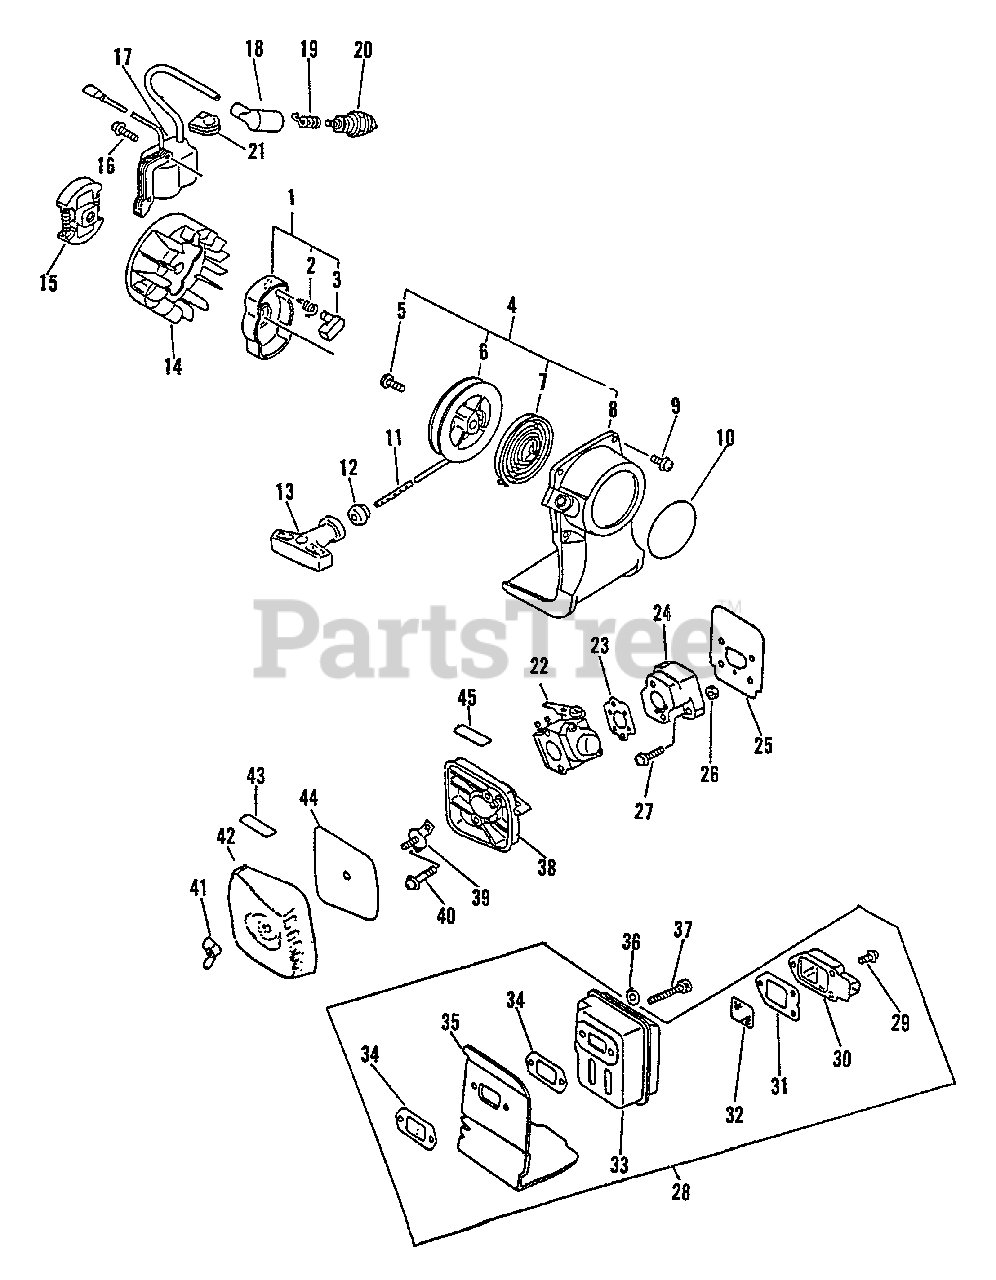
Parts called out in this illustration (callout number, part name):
1	PAWL ASSY, STARTER
2	SPRING, RETURN
3	PAWL, STARTER - BLACK
4	STARTER ASSY
5	SCREW
6	REEL, ROPE
7	SPRING, RECOIL
8	CASE, STARTER
9	SCREW 4×16
10	LABEL, ECHO
11	ROPE, STARTER
12	GUIDE, ROPE
13	GRIP, STARTER
14	FLYWHEEL
15	CLUTCH ASSY
16	SCREW 4×22
17	COIL, IGNITION
18	CAP, SPARK PLUG
19	TERMINAL, SPARK PLUG
20	SPARK PLUG - BPM7A
22	CARBURETOR - C1U-K16
23	GASKET, INTAKE
24	INSULATOR, INTAKE
25	GASKET, INTAKE
26	NUT M5
27	SCREW 5×20
28	MUFFLER ASSY
29	SCREW 4×10
30	GUIDE, EXHAUST - INNER
31	GASKET, EXHAUST
32	SCREEN, SPARK ARRESTER
33	MUFFLER
34	GASKET, EXHAUST
35	COVER, EXHAUST
36	WASHER, FLAT 5.5×10×0.8
37	BOLT 5×55
38	CASE, AIR FILTER
39	PLATE, PREVENT
40	SCREW 5×64
41	WINGNUT - 6
42	COVER, AIR FILTER
43	LABEL - TOP
44	FILTER, AIR
45	LABEL, CHOKE
